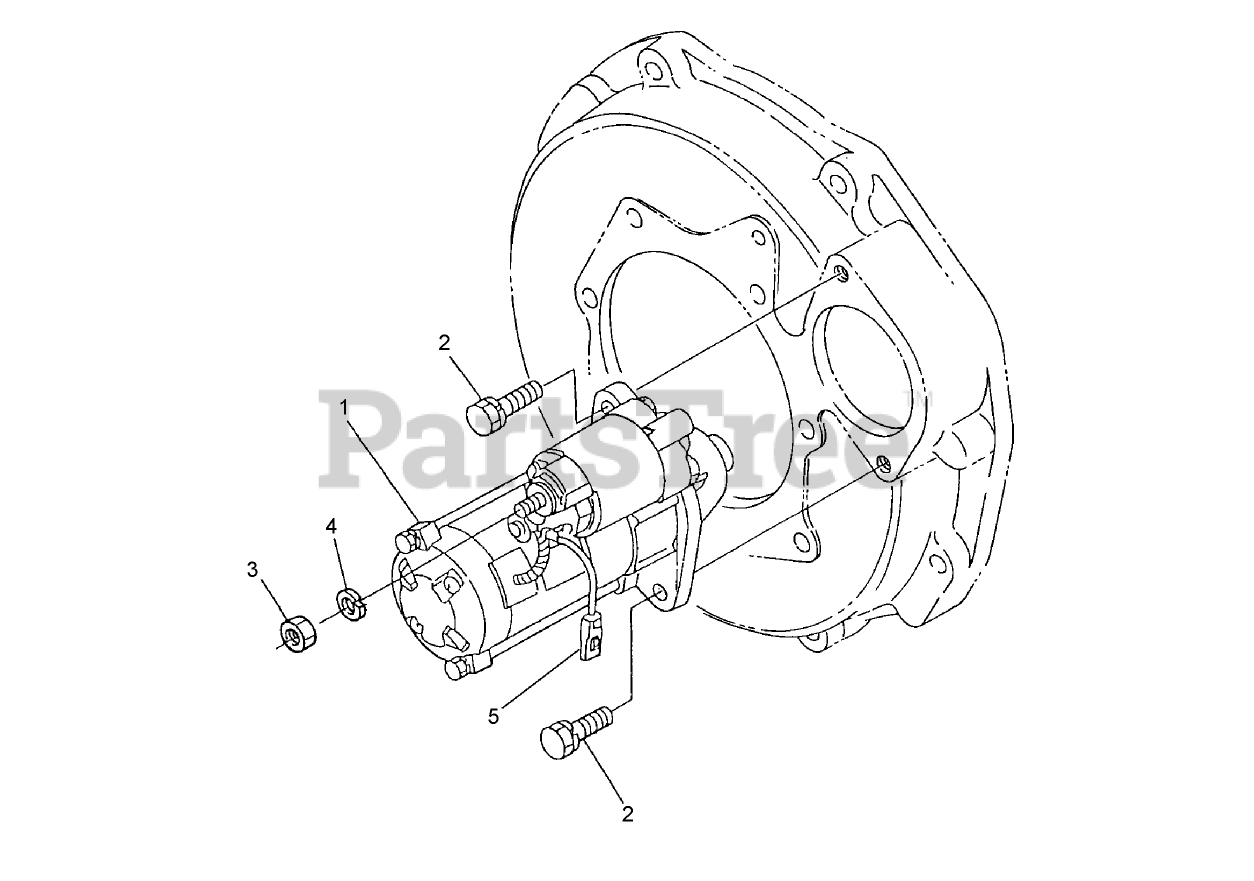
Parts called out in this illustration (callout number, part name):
1	STARTER ASM
4	WASHER-SPRING
5	WIRE-LEAD
